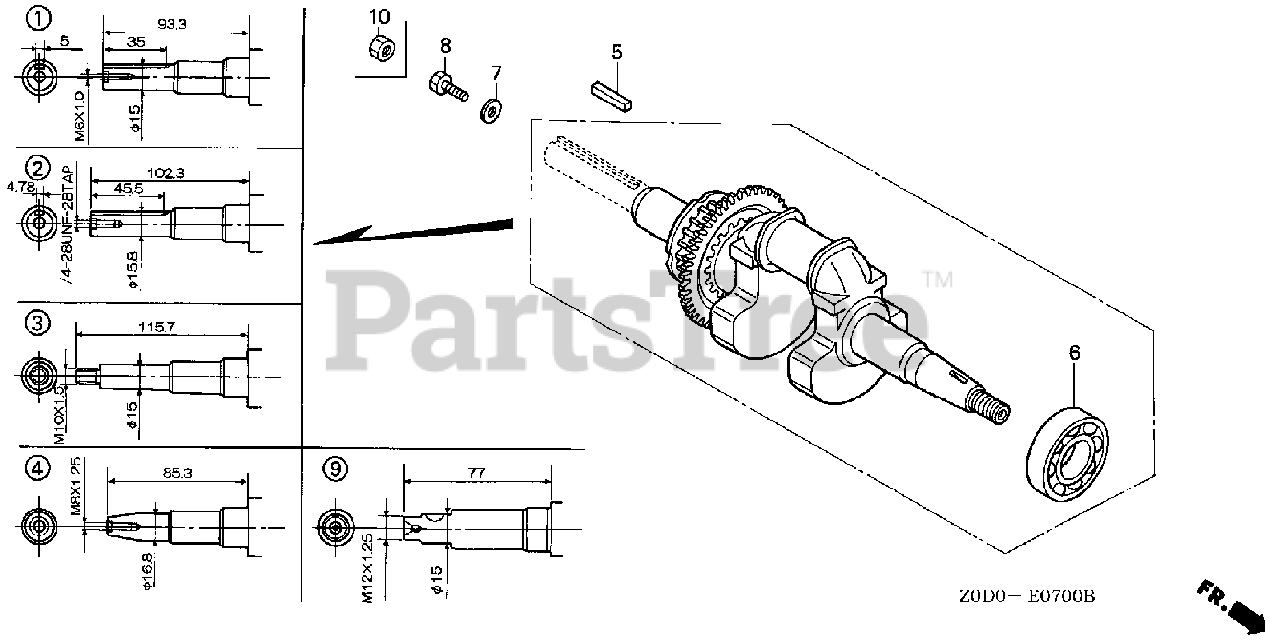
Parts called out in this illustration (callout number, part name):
2	CRANKSHAFT
5	KEY (4.78X4.78X38)
6	BEARING, RADIAL BALL (6204)
